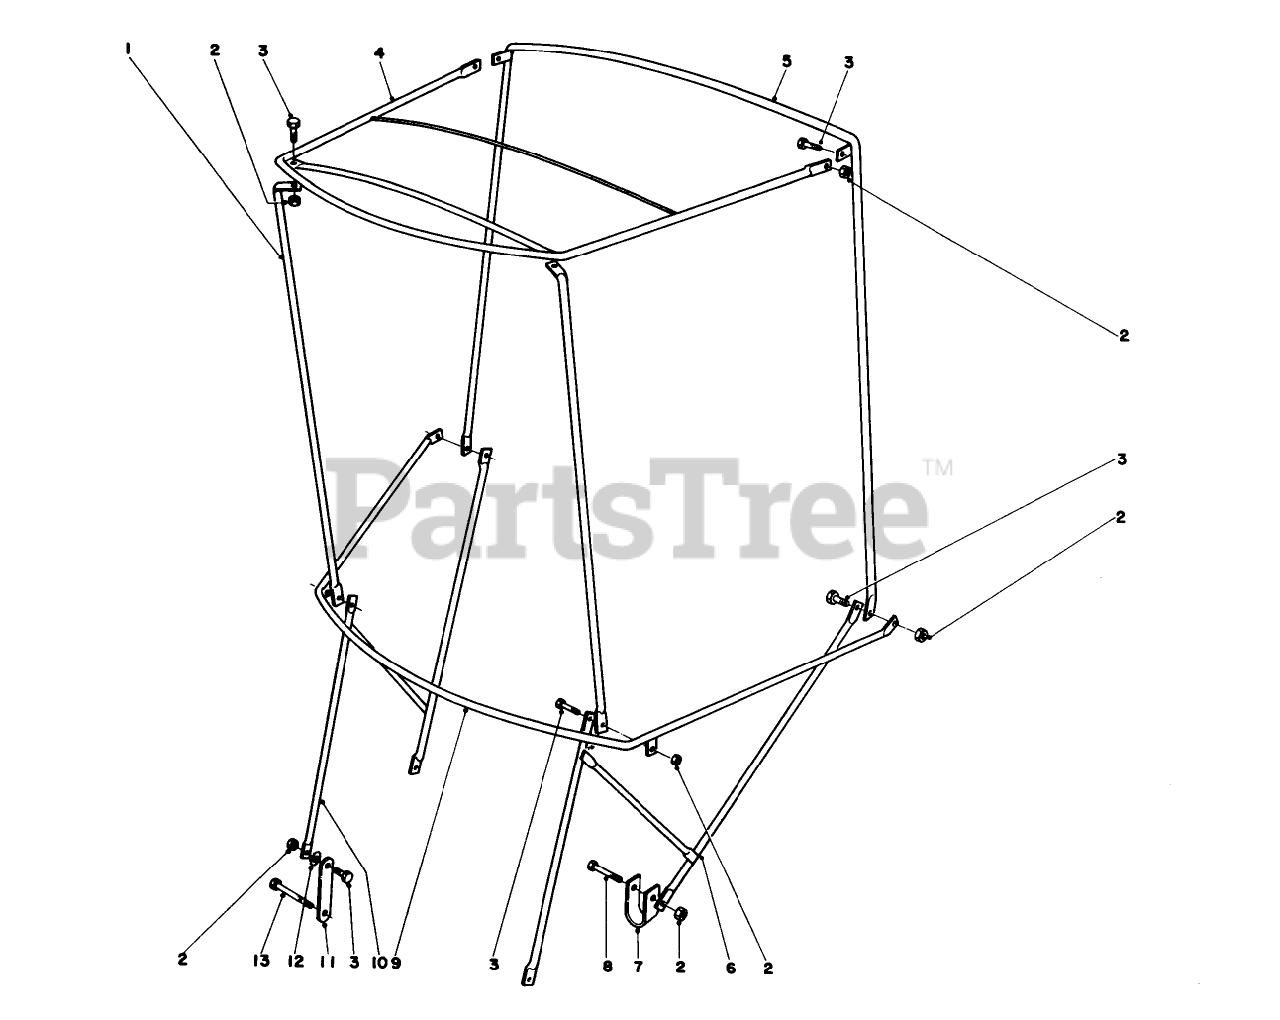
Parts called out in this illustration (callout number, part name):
3	SCREW-HH
8	SCREW-HH
12	WASHER-LOCK/EXT
13	SCREW-HH
